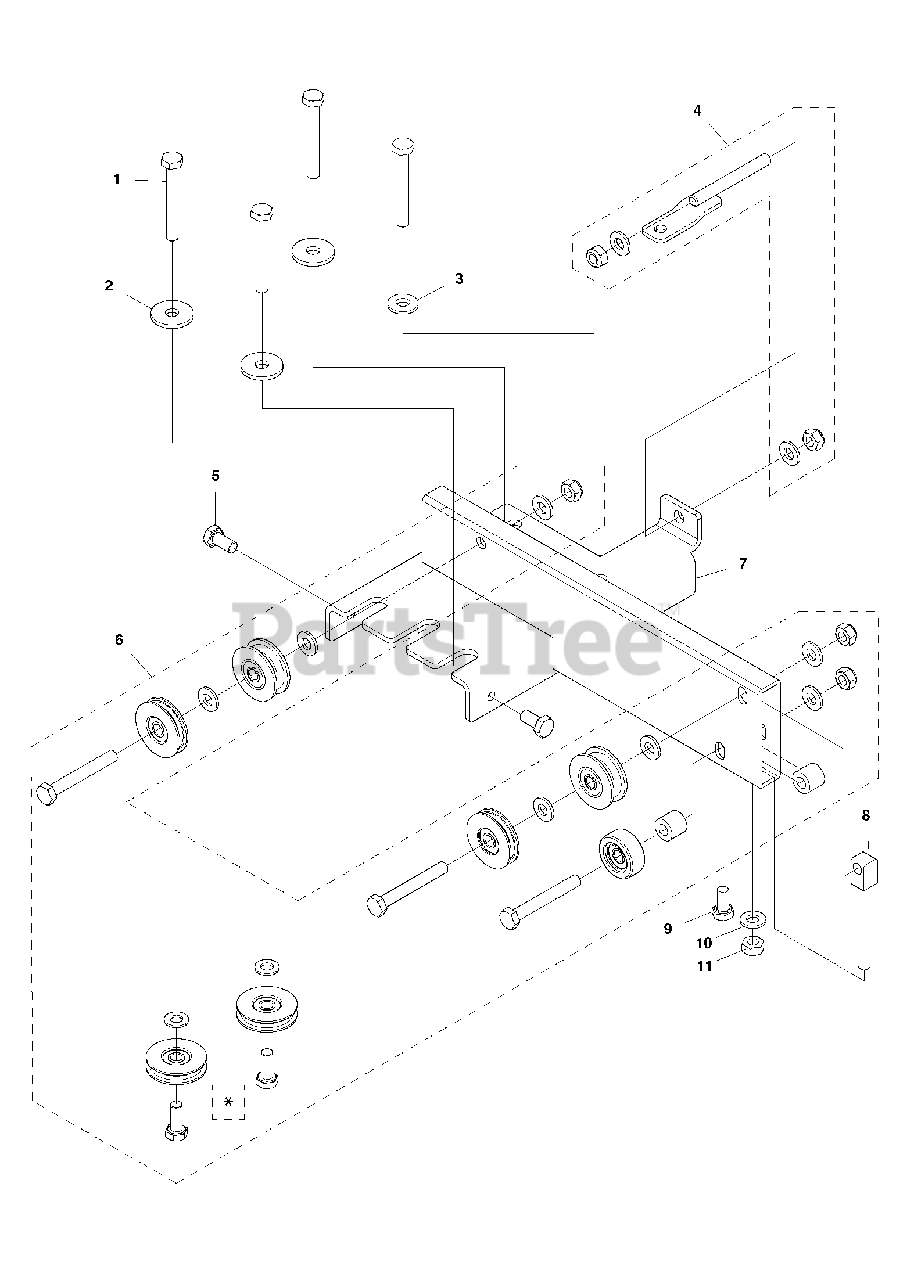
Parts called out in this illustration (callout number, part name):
5	SCREW EHHM
9	SCREW EHHM
10	WASHER
11	HEXAGON NUT
